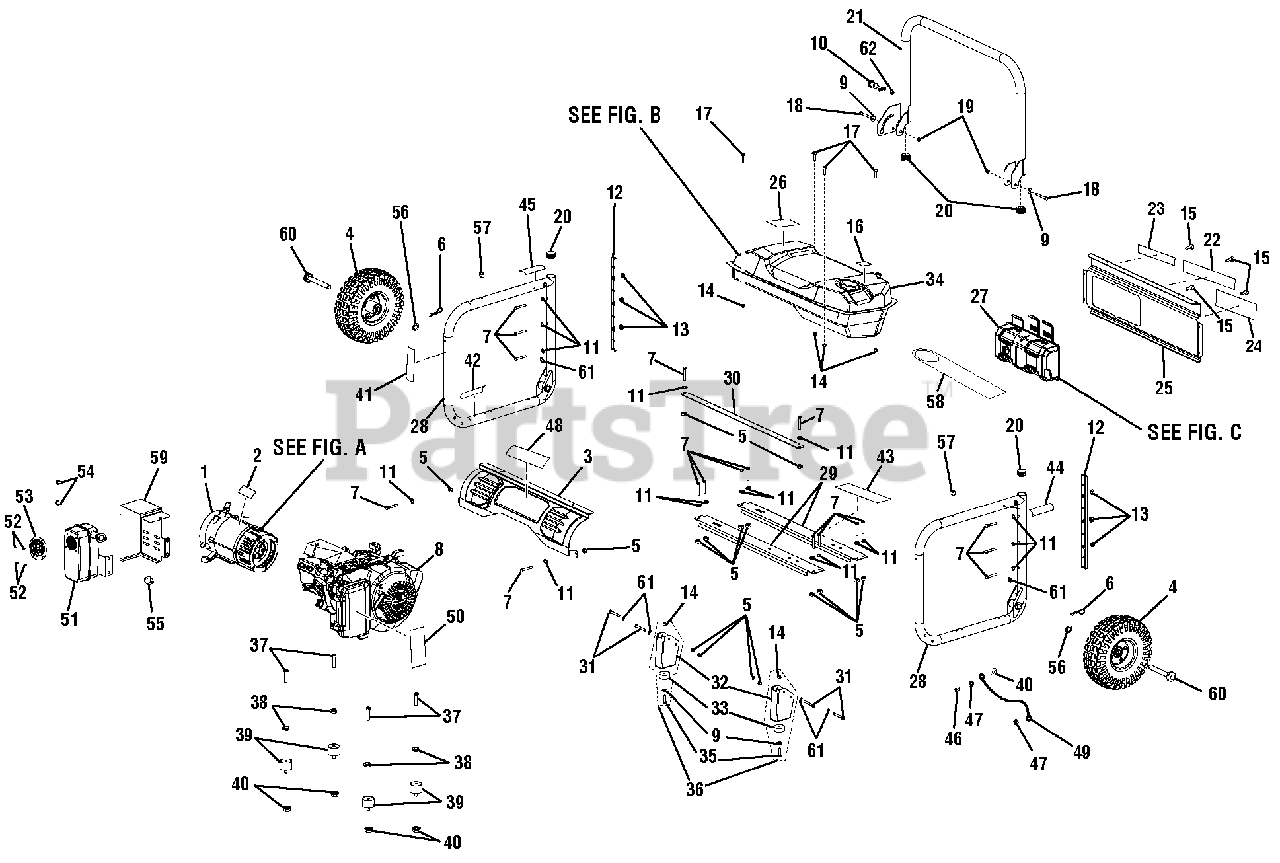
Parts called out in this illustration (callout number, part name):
1	Generator Head w/AVR
2	Data Label
3	Back Panel Assembly
5	Lock Nut (1/4-20)
6	Hitch Pin
7	Bolt (1/4-20 x 42.5 mm, Torx Hd.)
8	Engine (EX30 Subaru)
9	Washer (1/4 in.)
10	Handle Release Pin Assembly
11	Lock Washer (M6)
12	Frame Slide Rails
13	Hex Nut (1/4-20)
14	Lock Nut (1/4-20)
15	Screw (6-20 x 3/8 in., Pan Hd.)
16	E-85 Label
17	Bolt (1/4-14 x 1.25 in., Hex Hd.)
18	Bolt (M8 x 55 mm, Hex Hd.)
19	Lock Nut (M8)
21	Handle Assembly
22	Danger Label
23	Ground Warning Label
24	Logo Label
25	Control Panel
26	CPSC Label
27	Control Box (Front and Rear Assembly)
28	Frame Assembly
29	Frame Cross Brace
30	Back Frame Bracket
31	Bolt (1/4-20 x 2 in., T30 Torx Hd.)
34	Fuel Tank Assembly
35	Bolt (1/4-20 x 1 in., Hex Hd.)
36	Foot Assembly
37	Bolt (5/16-18 x 1-1/2 in.)
38	Lock Washer (5/16)
39	Isolator (Generator)
40	Flange Nut (5/16-18, Hex Hd.)
41	Hot Surface Label
42	Combustion Label
43	Lubricant Label
44	Fire Danger Label
45	Pin Release Label
46	Bolt (5/16-18 x 3/4 in.)
47	Star Washer (5/16 in.)
48	Back Panel Logo Label
49	Ground Wire Assembly
50	Starting Instruction Label
52	Spark Arrestor Screw
53	Spark Arrestor
54	Bolt (5/16-24 x 5/8 in.)
55	Muffler Gasket
56	Washer (5/8 x 1 x 5/8 in.)
57	Rubber Handle Bumper
58	Danger Hang Tag
59	Back Muffler Cover
61	Washer (1/4 in.)
62	Washer (OD20 x ID8 x 1t)
